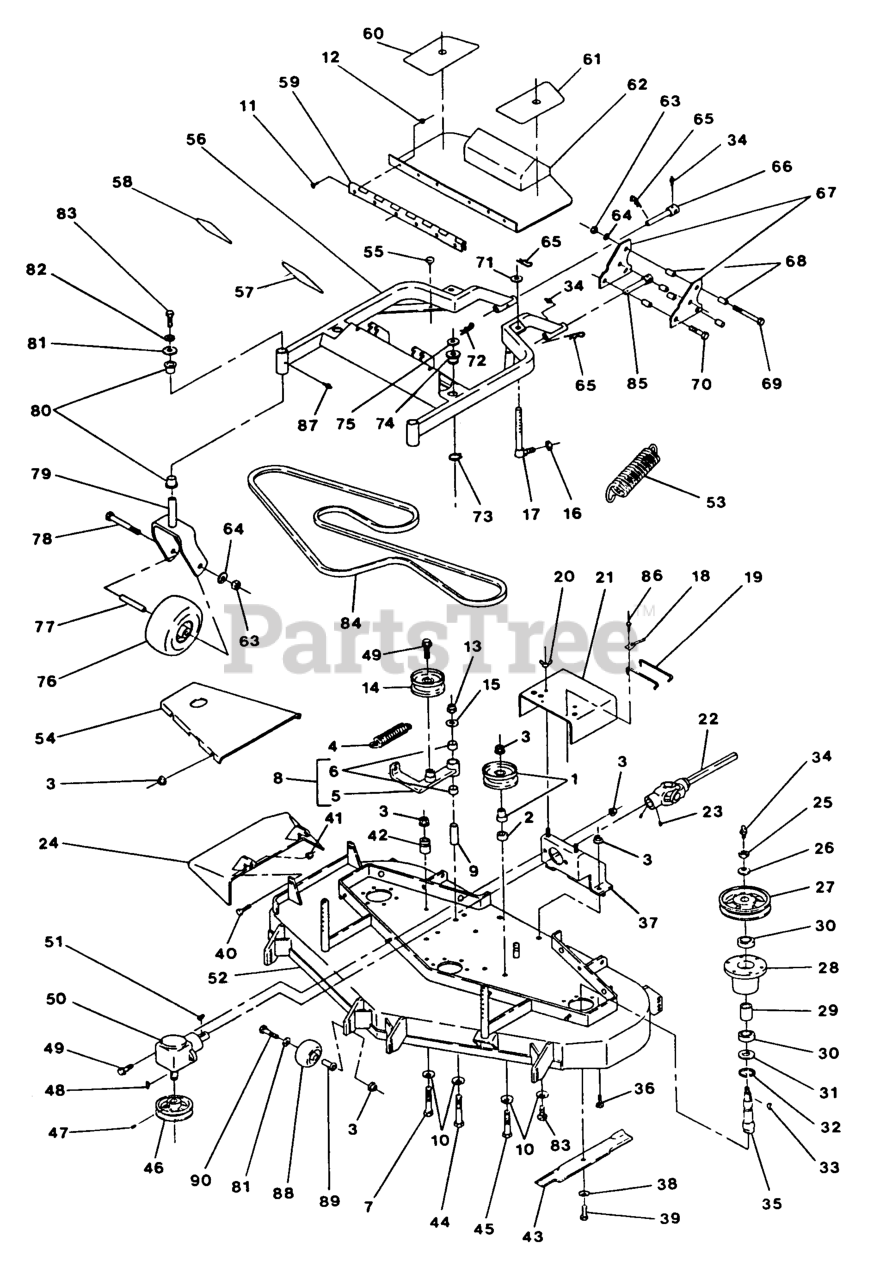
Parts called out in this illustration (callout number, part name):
1	KIT,48 RH IDLER/BUS
4	SPRING,EXTENSION
6	SLEEVE-BEARING
9	BUSHING
14	IDLER,PULLEY
18	CLIP-DECK, HOLD UP ROD
20	WINGNUT-NYLOCK
22	PTO SHAFT,SHAFT HALF PNT
24	WLD,CHUTE DISCHARGE
26	WASHER-SPRING
27	SHEAVE,BLADE DRIVE
29	SPACER,BEARING
31	SEAL,MECHANICAL DUST
32	RING,SNAP WLDS N5000-244
35	SPINDLE-OUTER BLADE
36	SCRW,TPTTE HH
37	WLD,GEARBOX SUPPORT
38	WASHER-SPRING
42	ANCHOR-SPRING PLTD
50	GEARBOX, PEERLESS
57	PAD,ANTI SKID UPPER LH
58	PAD,ANTI SKID UPPER RH
59	HINGE,FLOORPAN
60	PAD,ANTI SKID LOWER RH
65	PIN,HAIR COTTER
71	SPACER,REAR DK SUPP PLTD
74	BUSHING-DECK
86	Pop Rivet, Steel 3/16 X .250
88	ROLLER-SCALP, ANTI
89	BUSHING-ROLLER
90	SCRWCAPHH
